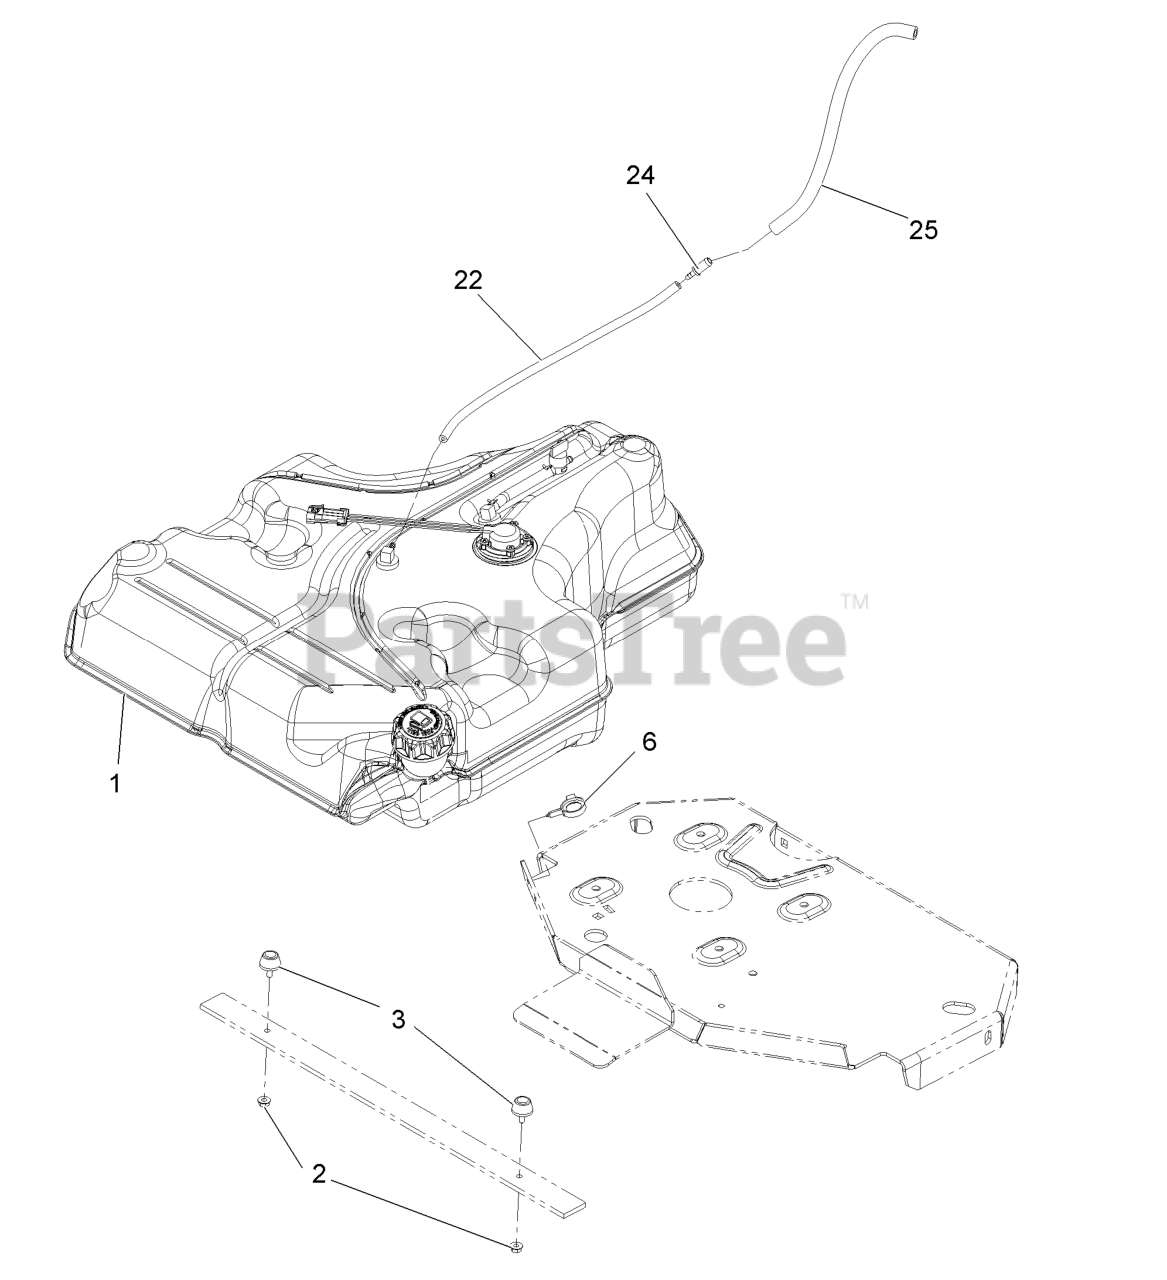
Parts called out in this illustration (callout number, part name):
3	BUMPER-RUBBER
6	CLAMP-HOSE
22	HOSE-FUEL
24	FITTING-STRAIGHT
25	HOSE-FUEL
